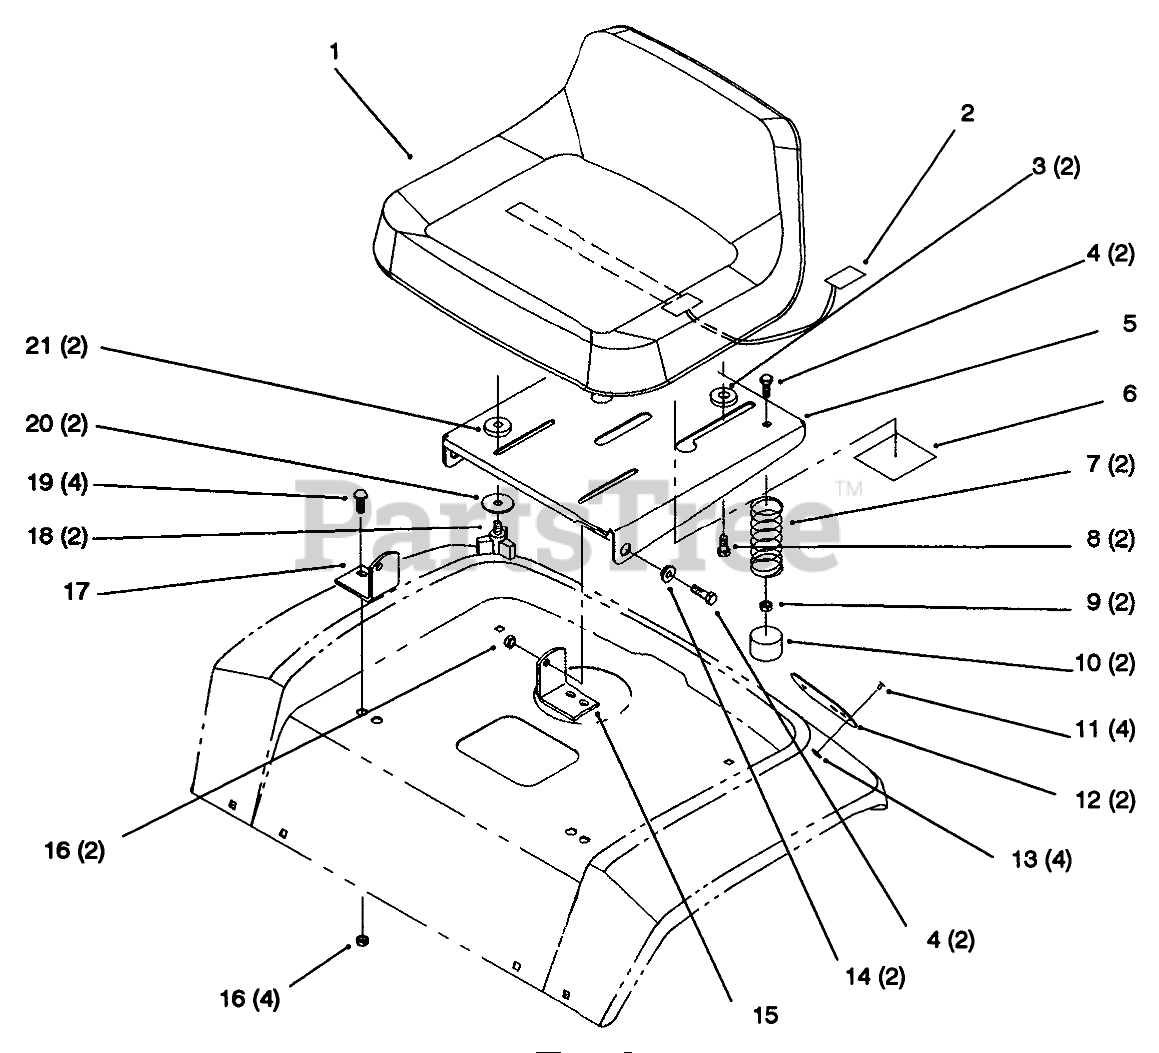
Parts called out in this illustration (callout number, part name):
1	SEAT-V-511
1:1	TRIM - SEAT
2	SWITCH-SEAT
3	SPACER-NYLON
4	SCREW-HH
5	Support-Seat
7	SPRING-COMPRESSION
8	BOLT-SHOULDER
9	NUT-LOCK, NI
10	CAP-PROTECTOR
11	RIVET-BLIND
12	REFLECTOR-STICK ON
13	WASHER-PLAIN
14	BUSHING
15	Bracket-Pivot LH
16	NUT-LOCK, NI
17	Bracket-Pivot RH
19	BOLT-CARR
20	WASHER
21	SPACER-NYLON
